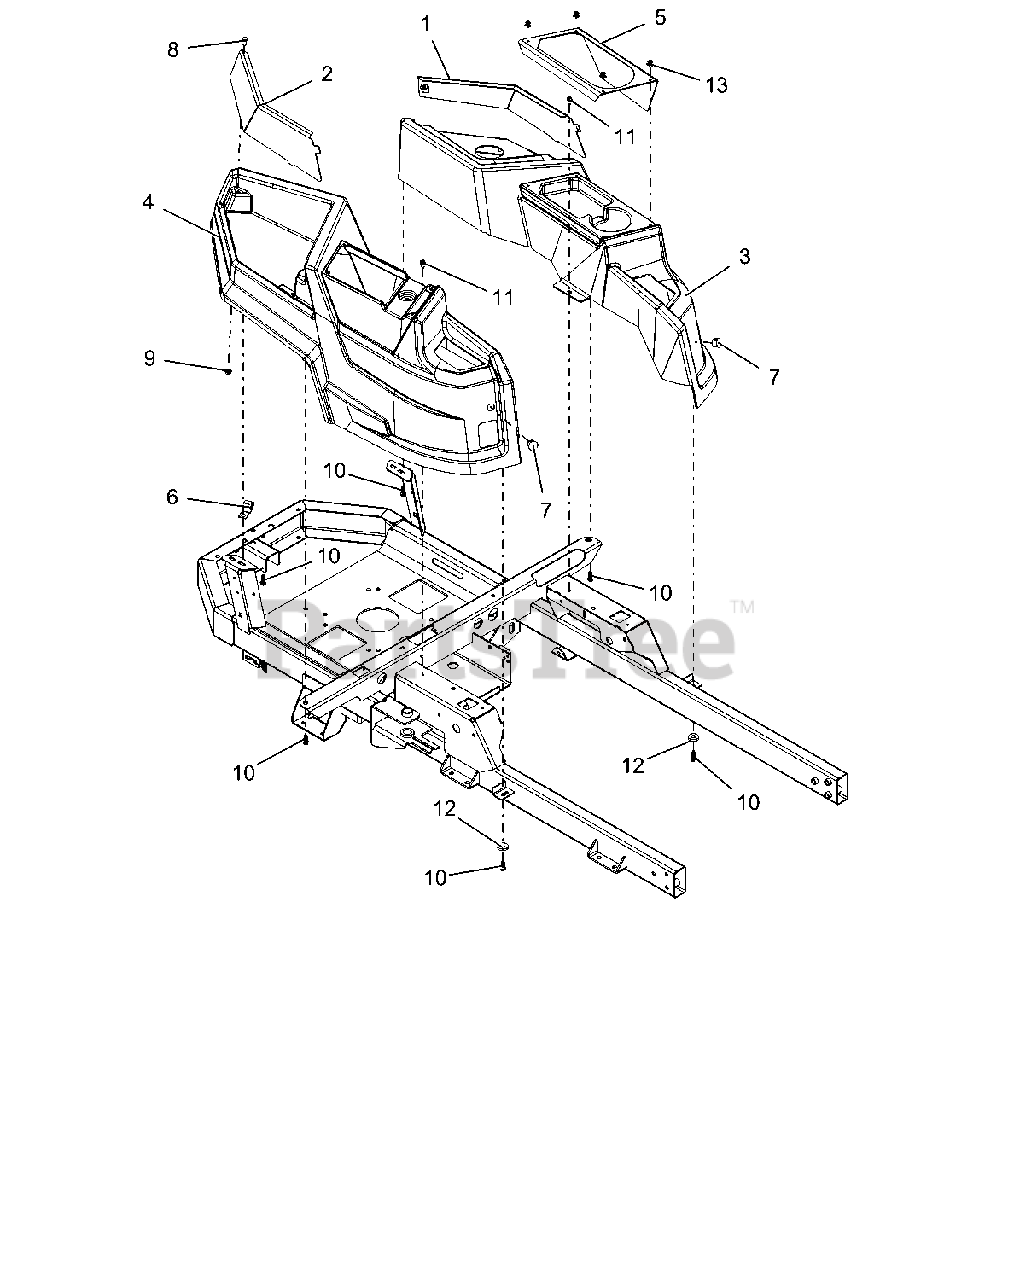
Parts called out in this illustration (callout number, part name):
1	WLDMT, PANEL BLOCK OFF-LH -RED
2	WLDMT, PANEL BLOCKOFF-RH (RED)
3	FENDER, LH -ZOOM
4	FENDER, RH -ZOOM
5	PANEL, CONTROL /CUP-LH
7	PLUG, HOLE .750-BLACK
8	BLT-HEX .25-20X.63 GR5 BLKZC
9	NUT, LK-TOP-FLG .25-20 YWZC
10	SCR-HEX .312-14X.75 H/L
11	SCR-TAP .25-20X.50 HWH TR YWZ
12	WSHR-FL-STL .406X1.00X.188 YWZC
13	RVT-POP .195 PLASTIC
